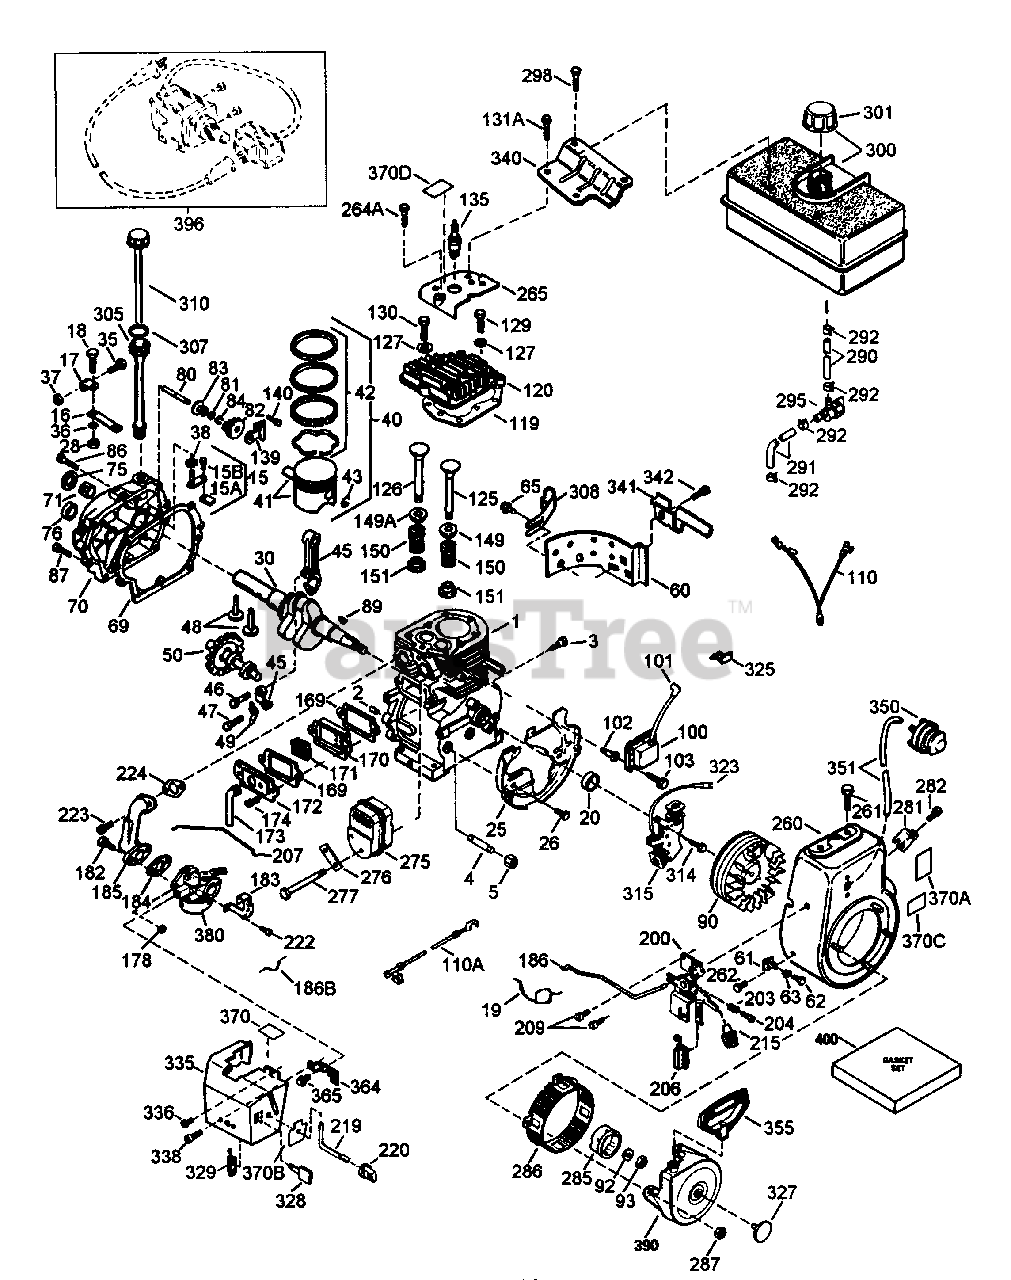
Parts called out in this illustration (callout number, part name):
1	Cylinder
2	Dowel Pin
3	Screw, 1/4-20 x 1/2"
4	Oil Drain Extension
5	Extension Cap
15	Governor Rod
15A	Governor Yoke
15B	Screw, 6-40 x 5/16"
16	Governor Lever
17	Governor Lever Clamp
18	Screw, 8-32 x 5/16"
19	Speed Control Spring
25	Blower Housing Baffle
26	Screw, 1/4-20 x 5/8"
28	Lock Nut, 8-32
30	Crankshaft
35	Screw, 10-32 x 3/4"
36	Lock Washer
37	Lock Nut, 10-32
38	Retaining Ring
40	Piston, Pin & Ring Set (Std.)
40	Piston, Pin & Ring Set (.010" OS)
40	Piston, Pin & Ring Set (.020" OS)
41	Piston & Pin Ass'y. (Std.)
41	Piston & Pin Ass'y. (.010" OS)
41	Piston & Pin Ass'y. (.020" OS)
42	Ring Set (Std.)
42	Ring Set (.010" OS)
42	Ring Set (.020" OS)
43	Piston Pin Retaining Ring
45	Connecting Rod Ass'y.
46	Connecting Rod Bolt
47	Connecting Rod Bolt
48	Valve Lifter
49	Oil Dipper
50	Camshaft (MCR)
60	Blower Housing Extension
61	Grommet Mounting Bracket
62	Screw, 8-32 x 3/8"
65	Screw, 10-24 x 1/2"
69	Cylinder Cover Gasket
70	Cylinder Cover
71	Crankshaft Bushing
76	Camshaft Seal
80	Governor Shaft
82	Governor Gear Ass'y.
83	Governor Spool
84	Retaining Ring
86	Screw, 1/4-20 x 1-3/16"
87	Screw, 1/4-20 x 1-11/16"
89	Flywheel Key
90	Flywheel (w/Ring Gear)
92	Lock Washer
93	Flywheel Nut
100	Solid State Ignition
101	Spark Plug Cover
102	Solid State Mounting Stud
103	Screw, Torx T-15, 10-24 x 15/16"
110	Ground Wire
110A	Ground Wire
119	Cylinder Head Gasket
120	Cylinder Head
125	Exhaust Valve (Std.)
125	Exhaust Valve (1/32" OS)
126	Intake Valve (Std.)
126	Intake Valve (1/32" OS)
129	Screw, 5/16-18 x 1-3/4"
130	Screw, 5/16-18 x 1-1/2"
131A	Screw, 5/16-18 x 5/8"
135	Resistor Spark Plug
139	Governor Gear Bracket
140	Screw, 10-24 x 1/2"
149	Valve Spring Cap
149A	Valve Spring Cap
150	Valve Spring
151	Valve Spring Keeper
169	Valve Cover Gasket
170	Breather Body
171	Breather Element
172	Valve Cover
173	Breather Tube
174	Screw, 10-24 x 1/2"
178	Nut and Lock Washer, 1/4-28
182	Screw, 1/4-28 x 1"
183	Choke Bracket
184	Carburetor
185	Intake Pipe
186	Governor Link
200	Control Bracket
203	Compression Spring
204	Screw, 5-40 x 7/16"
207	Throttle Link
209	Screw, 10-32 x 1/2"
215	Control Knob
219	Choke Rod
220	Choke Knob
222	Screw, 10-32 x 1/2"
223	Screw, Torx T-30, 5/16-18 x 1-1/8"
224	Intake Pipe Gasket
260	Blower Housing
261	Screw, 5/16-18 x 3/4"
262	Screw, Torx T-40, 5/16-24 x 21/32"
264A	Screw, 1/4-20 x 5/8"
265	Cylinder Head Cover
276	Locking Plate
277	Screw, 5/16-18 x 4-3/16"
281	Starter Bubble Cover
282	Screw, 8-32 x 3/8"
285	Starter Cup
286	Starter Screen
287	Nut & Lock Washer, 1/4-28
290	Fuel Line
291	Fuel Line
292	Fuel Line Clamp
295	Fuel Shut-Off Valve
298	Screw, 1/4-15 x 7/8"
300	Fuel Tank
301	Fuel Cap
305	Oil Fill Tube
308	Fill Tube Clip
314	Screw, 1/4-20 x 3/4"
315	Alternator Coil (18 Watt)
325	Wire Clip
327	Logo Decal
328	Ignition Key
335	Carburetor Cover
336	Screw, 10-32 x 1/2"
338	Screw, 10-32 x 3/8"
340	Fuel Tank Bracket
341	Fuel Tank Bracket
342	Screw, 1/4-20 x 5/8"
350	Primer Ass'y.
351	Primer Line
355	Starter Handle
364	Carburetor Cover Bracket
365	Screw, 8-32 x 27/64"
370	Instruction Decal
370A	Primer Decal
370B	Instruction Decal
370C	Warning Decal
370D	Lubrication Decal
380	Carburetor
390	Rewind Starter
396	Electric Starter Motor
400	Gasket Set
